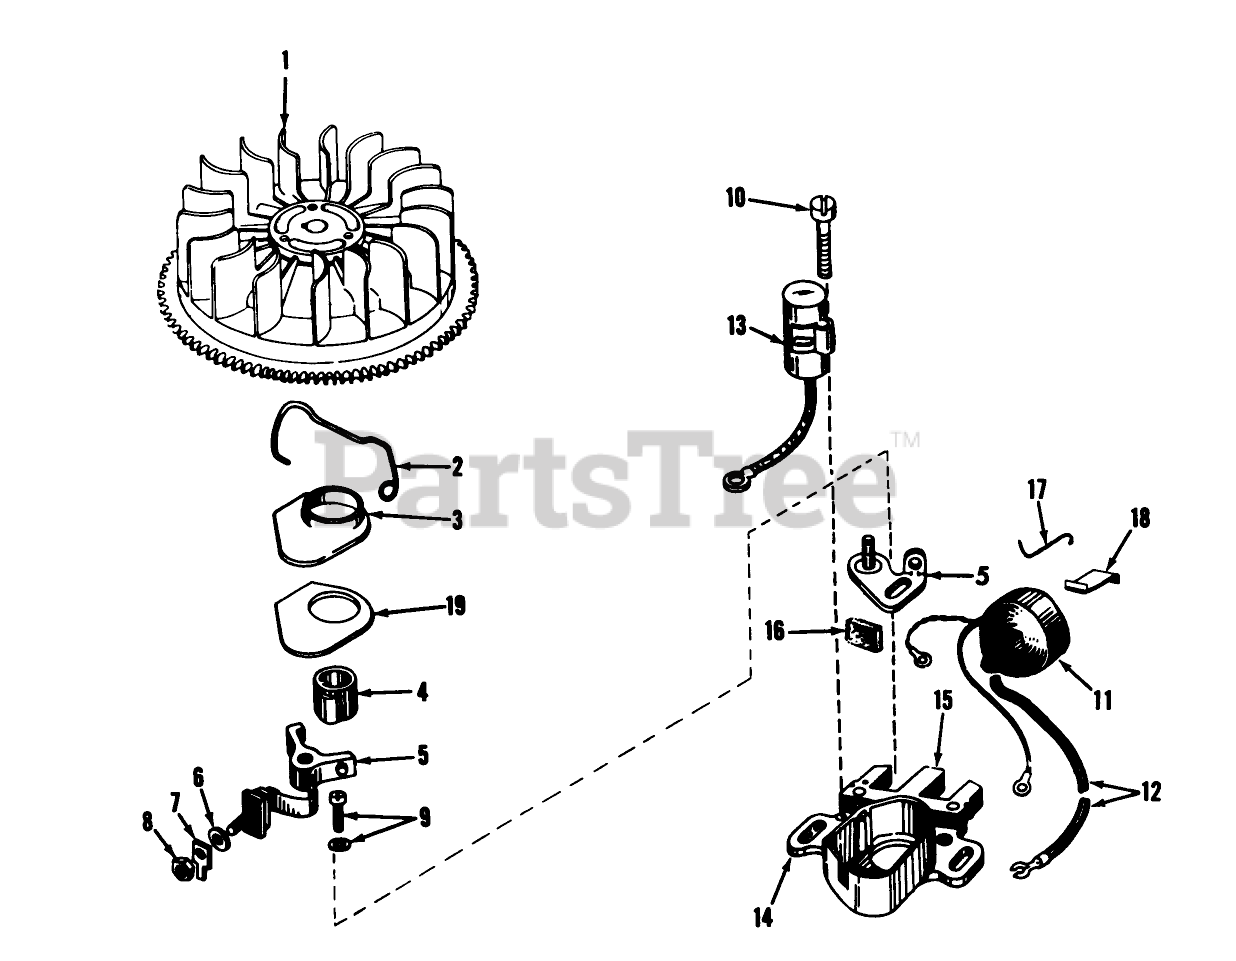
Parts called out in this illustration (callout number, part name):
1	Flywheel
2	Spring Breaker Box
3	Cover, Dust
4	Cam-Breaker
5	Breaker Assy.
6	Washer
7	Terminal
8	DECAL
9	Breaker Screw
10	Condenser Screw
11	Coil Assy. (Incl. No. 12)
12	Wire, Lead
13	Condenser
14	Core Plate
15	Stator Assy., (Incl. Nos. 2, 3, 5 thru 14 16 thru 19)
16	Felt,Cam Wiper
17	Clip, Coil
18	Spring Coil Wedge
19	Gasket, Dust Cover
